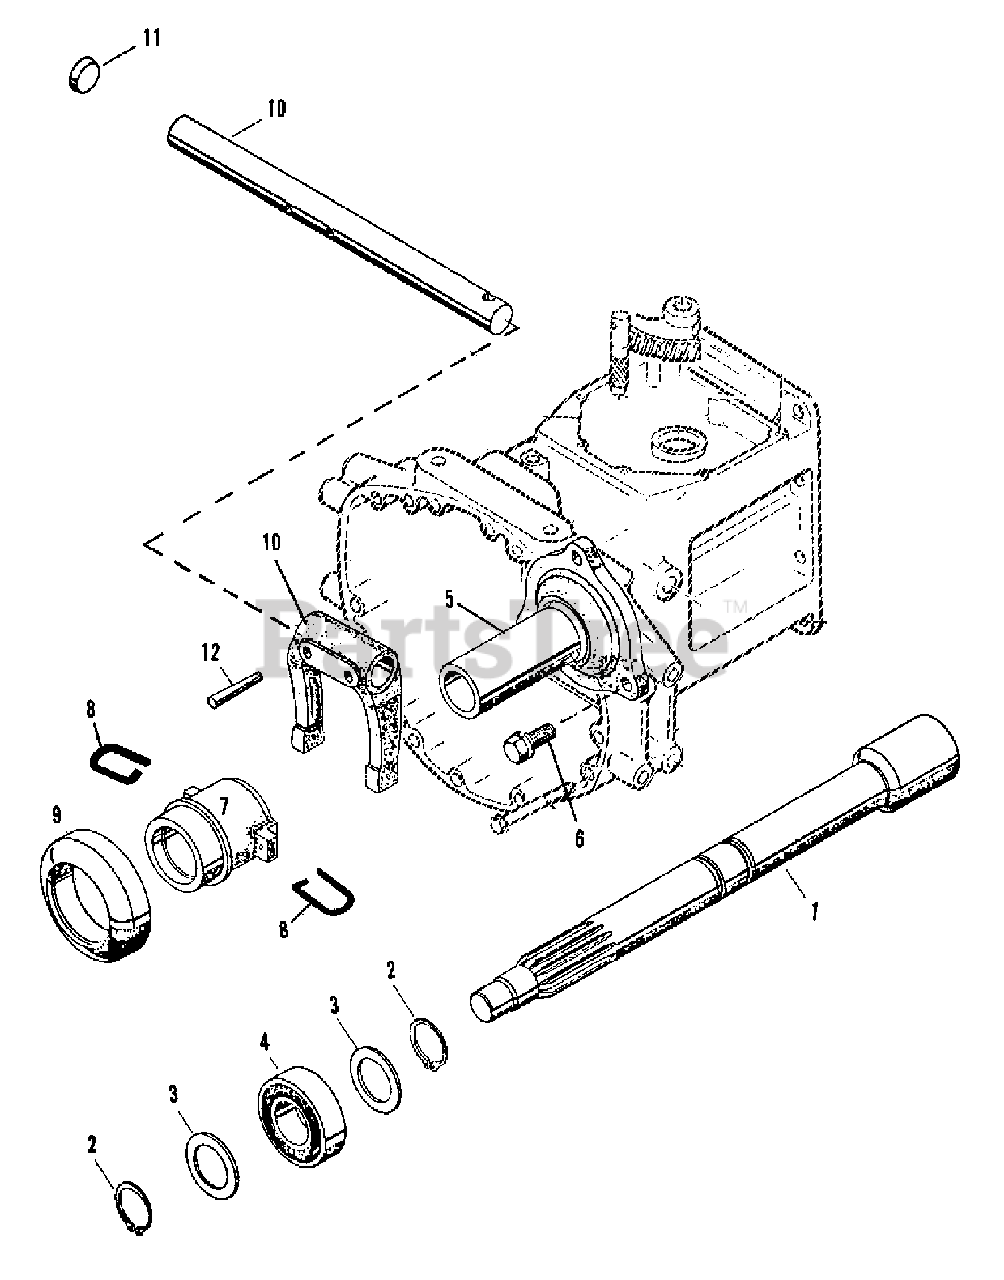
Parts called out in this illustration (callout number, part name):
1	SHAFT, input
2	RING, M25, snap, external
3	WASHER, THRUST
4	BEARING, ball (Seal type)
5	GUIDE, release bearing
6	CAPSCREW, M8 x 22, w/lockwasher
7	SLEEVE, release bearing
8	SPRING, return
9	BEARING, release - clutch
10	SHIFTER ASSEMBLY, (Incl. Item 10 & 11)
12	PIN, tapered
